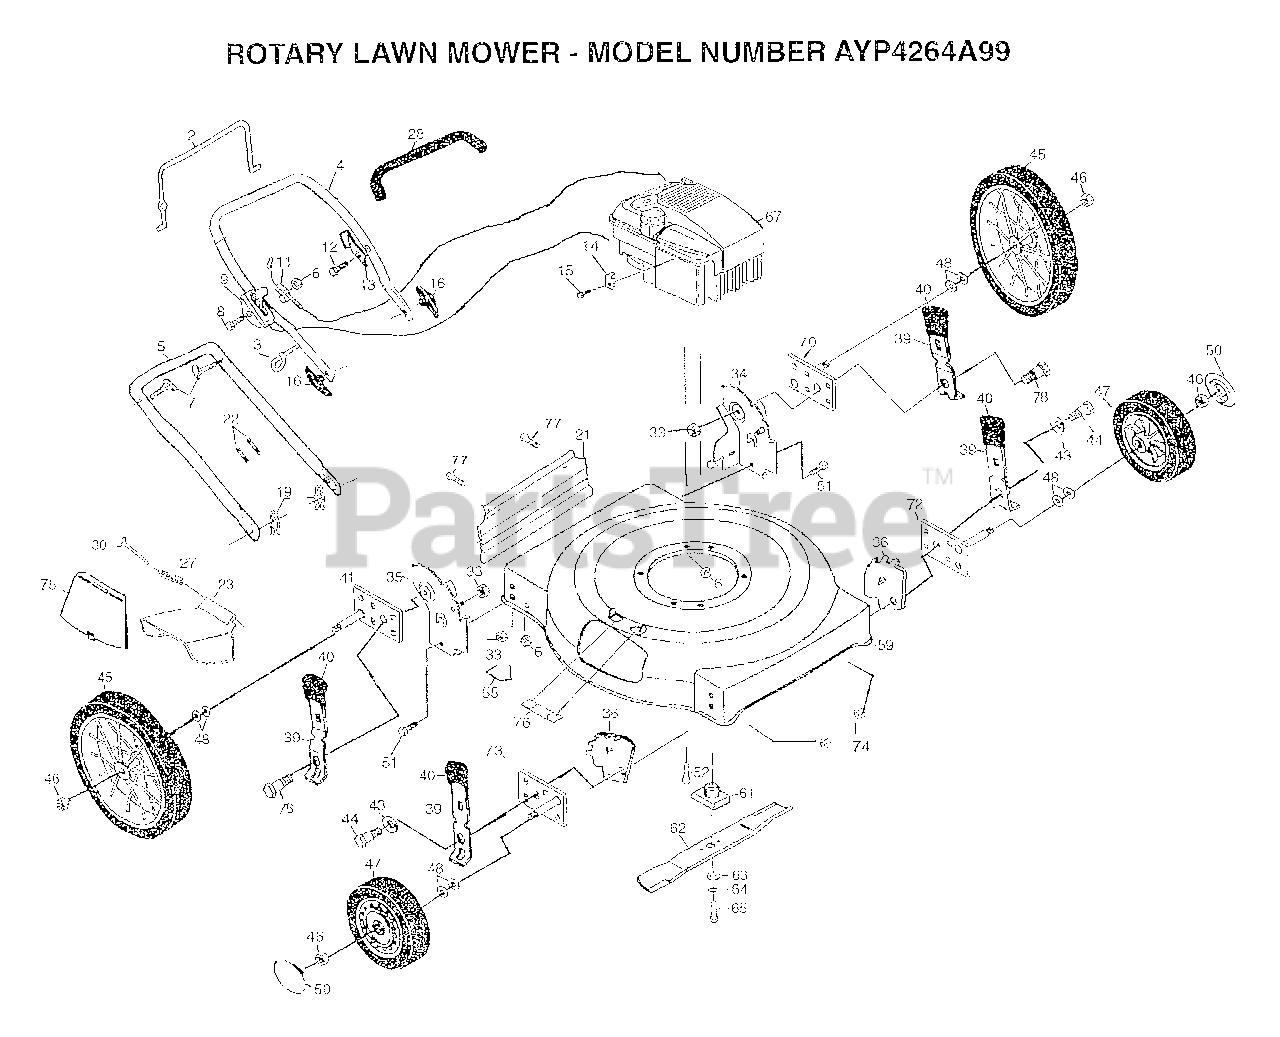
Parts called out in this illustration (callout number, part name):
2	CONTROL BAR PM
3	ROPE GUIDE
4	UPPER HANDLE
5	LOWER HANDLE
7	BOLT.HANDLE.LM
8	SCREW.HXHD.WASH.
9	CONTROL.THRT.45.6
11	CABLE.MZR.48.5
12	TAPPING SCREW
13	"BRKT,UPSTOP"
14	CABLE CLAMP
15	SCREW PM
16	KNOB HANDLE
19	HAIRPIN COTTER
21	"SKIRT.REAR.22SD/ECON.21"""
23	GUARD.DISCHARGE
27	HINGE.SPRING
28	GRIP.HANDLE.FOAM
30	HINGE.ROD.22SD
36	WHEEL.BRKT.ADJ.
39	SPRING.SELECTOR.5/9POS
40	KNOB PM
41	ASM.AXLE.ARM.
43	WASHER.BELLEVELLE
44	SHOULDER BOLT
45	WHEEL & TIRE PM
46	HEX FLANGE LOCKNT
47	WHEEL & TIRE PM
48	WAVE WASHER
50	HUB CAP
51	BOLT
52	BOLT.ENG.3/8-16
55	DECAL-DANGER PM
59	LAWN MOWER HOUSING
61	ADAPTOR.BLADE.LM
62	"BLADE.MULCH.22"""
63	"WASHER,HARDEN"
64	LOCKWASHER
65	SCREW
70	AXLE.ARM.ASSY.LR
72	ARM.ASM.AXLE.RR/LF.
73	ARM.ASM.AXLE.LR/RF
74	LOCKNUT
75	MULCHER PLATE
76	CLIP.CLOSECUT.22SD
77	BOLT LT
78	SHOULDER.BOLT
